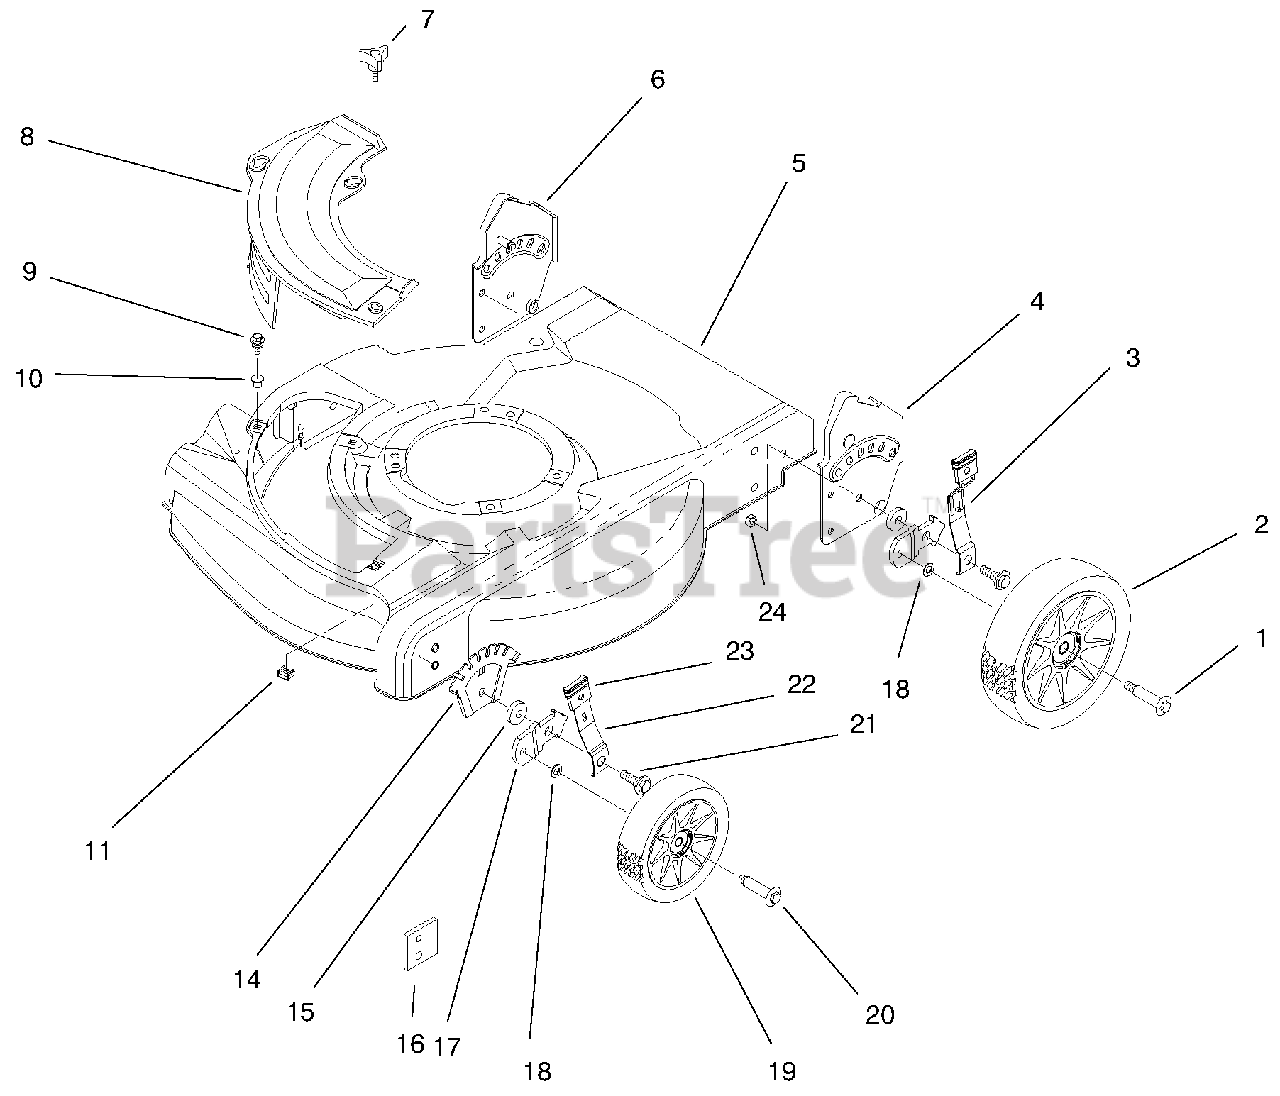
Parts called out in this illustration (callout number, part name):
1	Bolt-Shoulder
2	ASM-Wheel
3	ASM-Spring Arm
4	ASM-Handle Brkt
5	ASM-Housing & Baffle
6	ASM-Handle Brkt
7	Knob-Cover Plate
8	Mulch Plate-21"
9	Screw-Sems
10	Grommet-Plastic
11	Nut-Cage
14	Plate-Height Adjust
16	Plate-Baffle
17	Bracket-Wheel Height Adj
19	ASM-Wheel & Tire 6"
20	Bolt-Shoulder 6" Wheel
21	Bolt-Shoulder
22	Spring Arm-Front
23	Knob-Height Adjust
24	Nut-Lock
